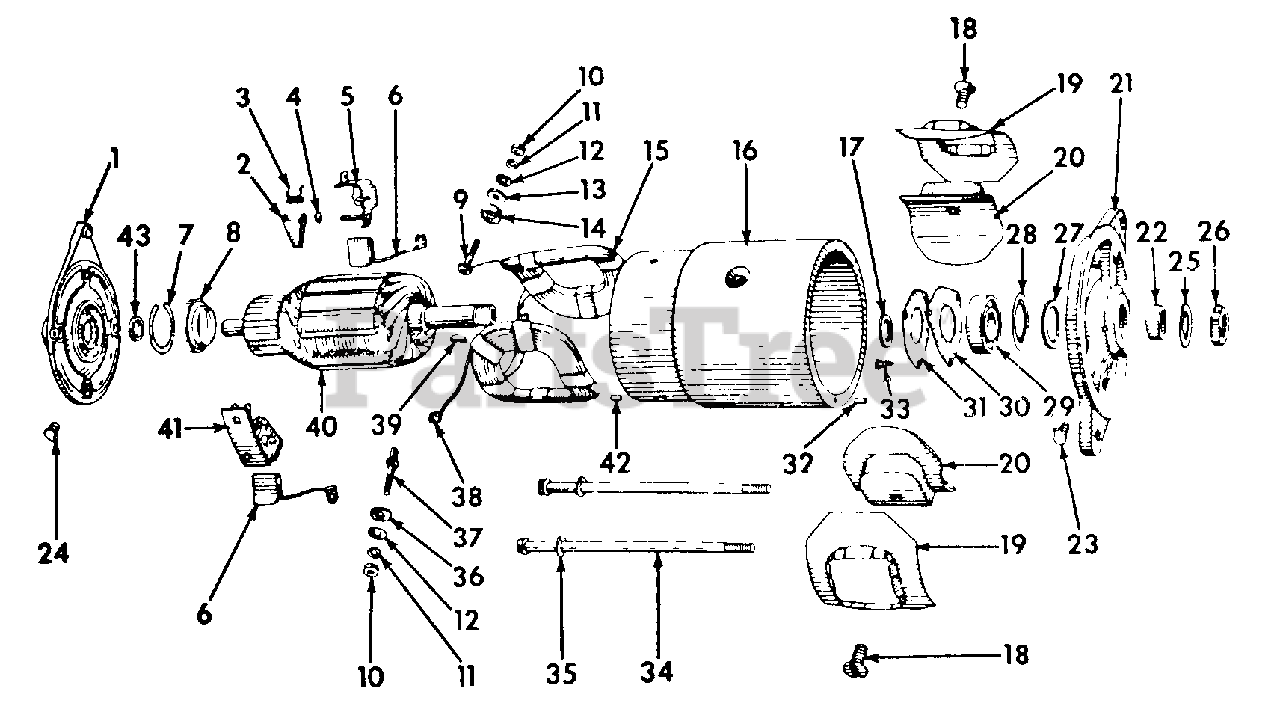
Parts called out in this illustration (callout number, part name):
1	FRAME ASSY, COMMUTATOR END
3	SPRING, BRUSH
4	WASHER, BRUSH ARM SPACE
5	HOLDER, GROUND BRUSH
7	WICK, COMMUTATOR END OIL
8	RETAINER, COMMUTATOR END
9	STUD, FIELD TERMINAL
10	NUT, 12-24 C-Z HEX
11	WASHER FIELD TERMINAL STUD LOCK
12	WASHER, TERMINAL STUD
13	WASHER, TERMINAL STUD INSULATING
14	BUSHING, TERMINAL STUD INSULATING
15	COIL SET, FIELD
16	FRAME NOT SERVICED SEPARATELY
17	WASHER, DRIVE END SPACE
18	SCREW, POLE SHOE
19	INSULATOR, FIELD COIL
21	FRAME, DRIVE END
22	COLLAR, DRIVE END SPACE
23	OILER, DRIVE END BEARING
24	OILER, COMMUTATOR END
25	WASHER, ARMATURE SHAFT NUT LOCK
26	NUT, ARMATURE SHAFT
27	WASHER, DRIVE END FELT
28	RETAINER, DRIVE END FELT WASHER
29	BEARING, DRIVE END BALL
30	GASKET, BALL BEARING RETAINER PLATE
31	PLATE, BALL BEARING BEARING RETAINER
32	PIN, DRIVE END FRAME DOWEL
33	SCREW, BEARING RETAINER PLATE
35	WASHER, 5/16 C-Z HEAVY LOCK
36	BUSHING, ARMATURE TERMINAL STUD INSULATING
37	STUD, ARMATURE TERMINAL
38	CLIP TERMINAL TO BRUSH
39	KEY, 1/8 X 5/8 WOODRUFF NO. 5 ALY-S
40	ARMATURE
41	HOLDER, INSULATED BRUSH
42	PIN, COMMUTATOR END FRAME DOWEL
43	SEAL, COMMUTATOR END OIL
